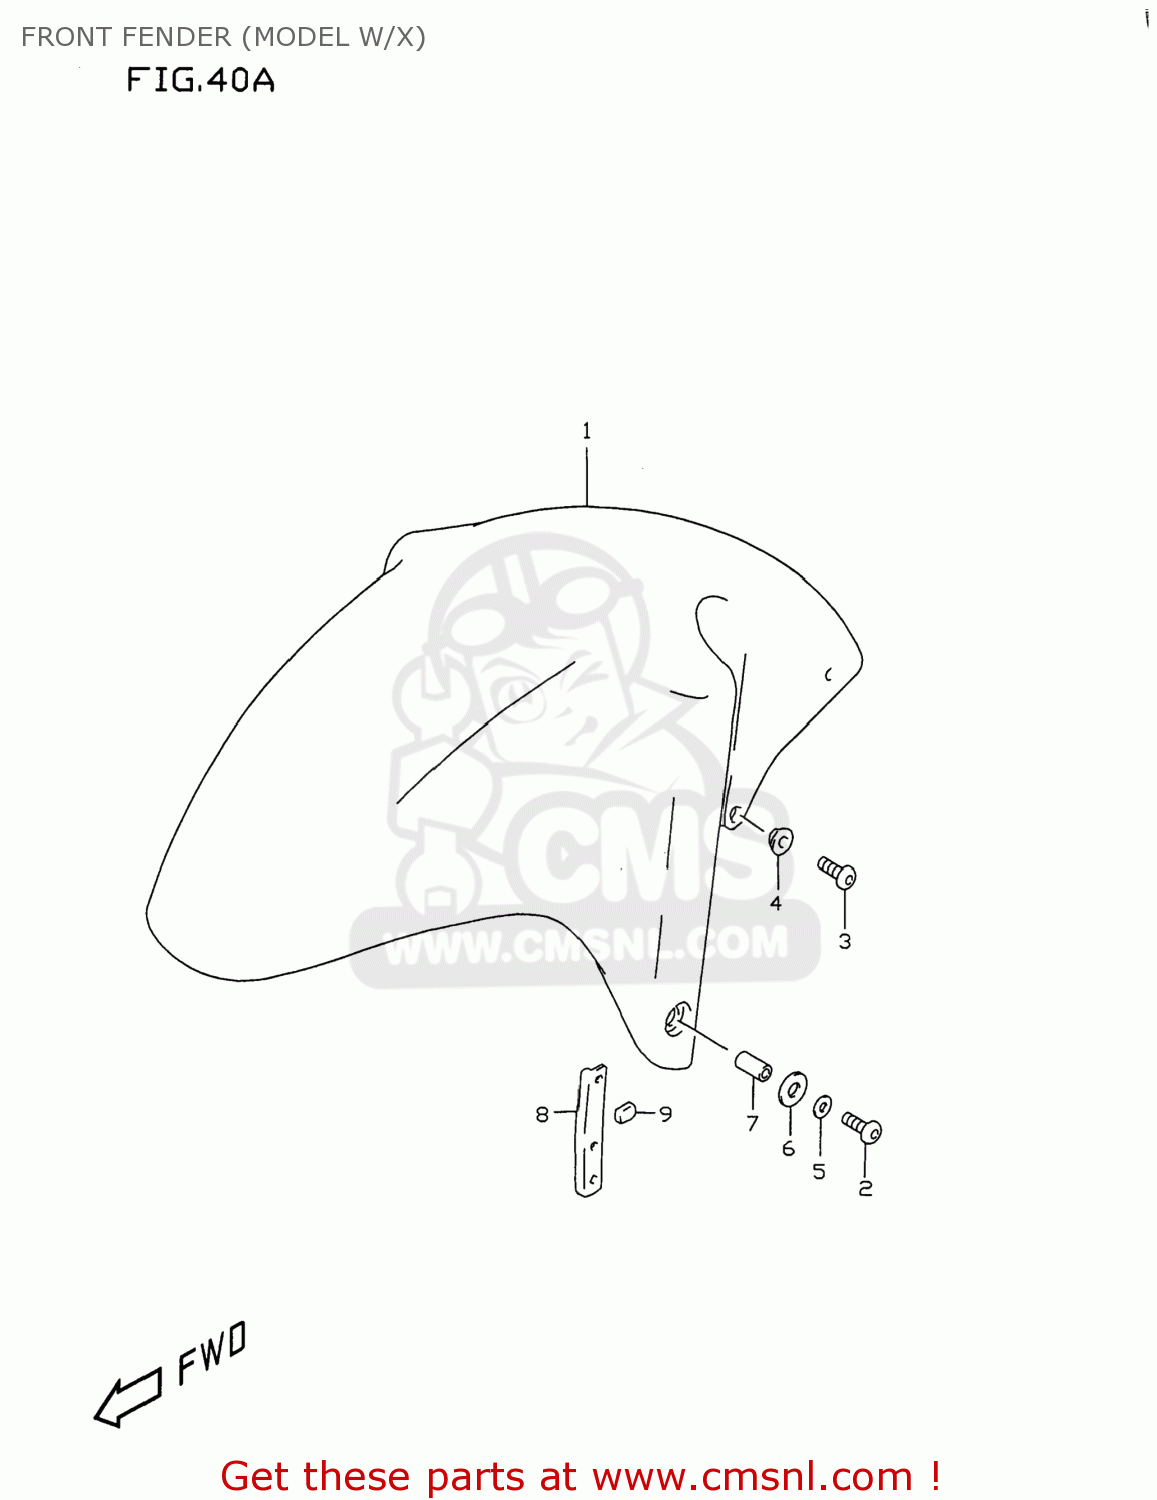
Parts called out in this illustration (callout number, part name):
1	FENDER,FR
2	SCREW(6X20)
3	SCREW(6X16)
4	WASHER(6.3X16X1.5)
5	WASHER(6.5X16X1.2)
6	WASHER,FR FENDER FR NO.2
7	SPACER(6.5X9X6.7)
8	PLATE,FRONT FENDER
9	CUSHION
